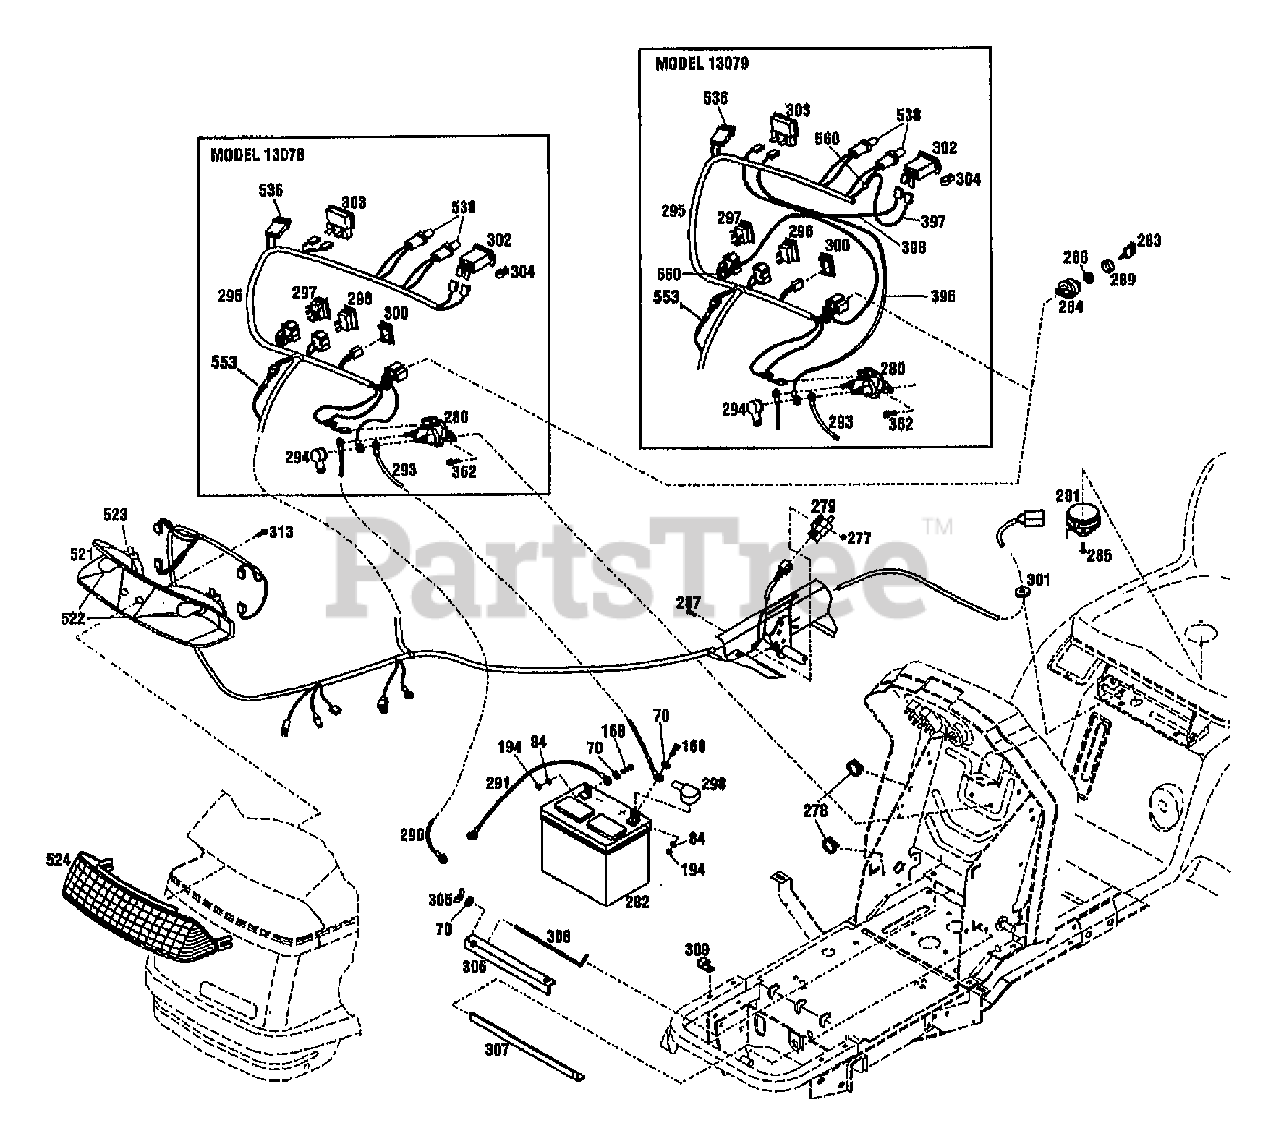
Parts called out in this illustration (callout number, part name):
70	WASHER-FLAT 1/4 SAE
84	WASHER-LK .25 ZP
168	SCR-HH 1/4-20X.75 G5 ZP
194	NUT-HEX 1/4-20 ZP
277	NUT W/LKWASHER 10-24 ZP
278	TIE-CABLE NYLON BLACK
279	SWITCH
280	SOLENOID
281	SWITCH-SEAT
282	BATTERY {13078}
282	BATTERY {13079}
283	KEY-IGNITION
284	SWITCH-IGNITION
285	SCR-PHP 1/4-20X.50 ZP
287	SCR-HHS 10-24X.625 ZP
288	NUT-SWITCH
289	CAP-SWITCH
290	CABLE-STARTER
291	CABLE-BATTERY (-)
293	CABLE-BATTERY
294	BOOT-SOLENOID
295	HARNESS-MAIN ELECTRICAL {13078}
295	HARNESS-MAIN WIRING {13079}
296	SWITCH-LIGHT
297	SWITCH-PTO
298	BOOT-TERMINAL
300	COVER-SWITCH
301	GROMMET
302	METER-HOUR
303	AMMETER
304	CLIP-TINNERMAN
305	NUT-WING
306	CLAMP-BATTERY
307	BRKT-BATTERY LOWER
308	SCR-HOOK
309	CLIP-J
362	SCR 1/4-20X.5 FL SELF TAP
396	ASSM-WIRE LEAD(1768854) {13079}
397	ASSM-BLACK WIRE LEAD {13079}
398	ASSM-RED LEAD WIRE {13079}
521	HEADLGT-REFL (PART OF 1772002)
522	LIGHTBULB
523	SOCKET
524	LENSE-HEADLIGHT
536	BRKT-MTG HGT ADJ
538	LIGHTBULB
553	ASSM-DIODE
560	CONNECTOR
